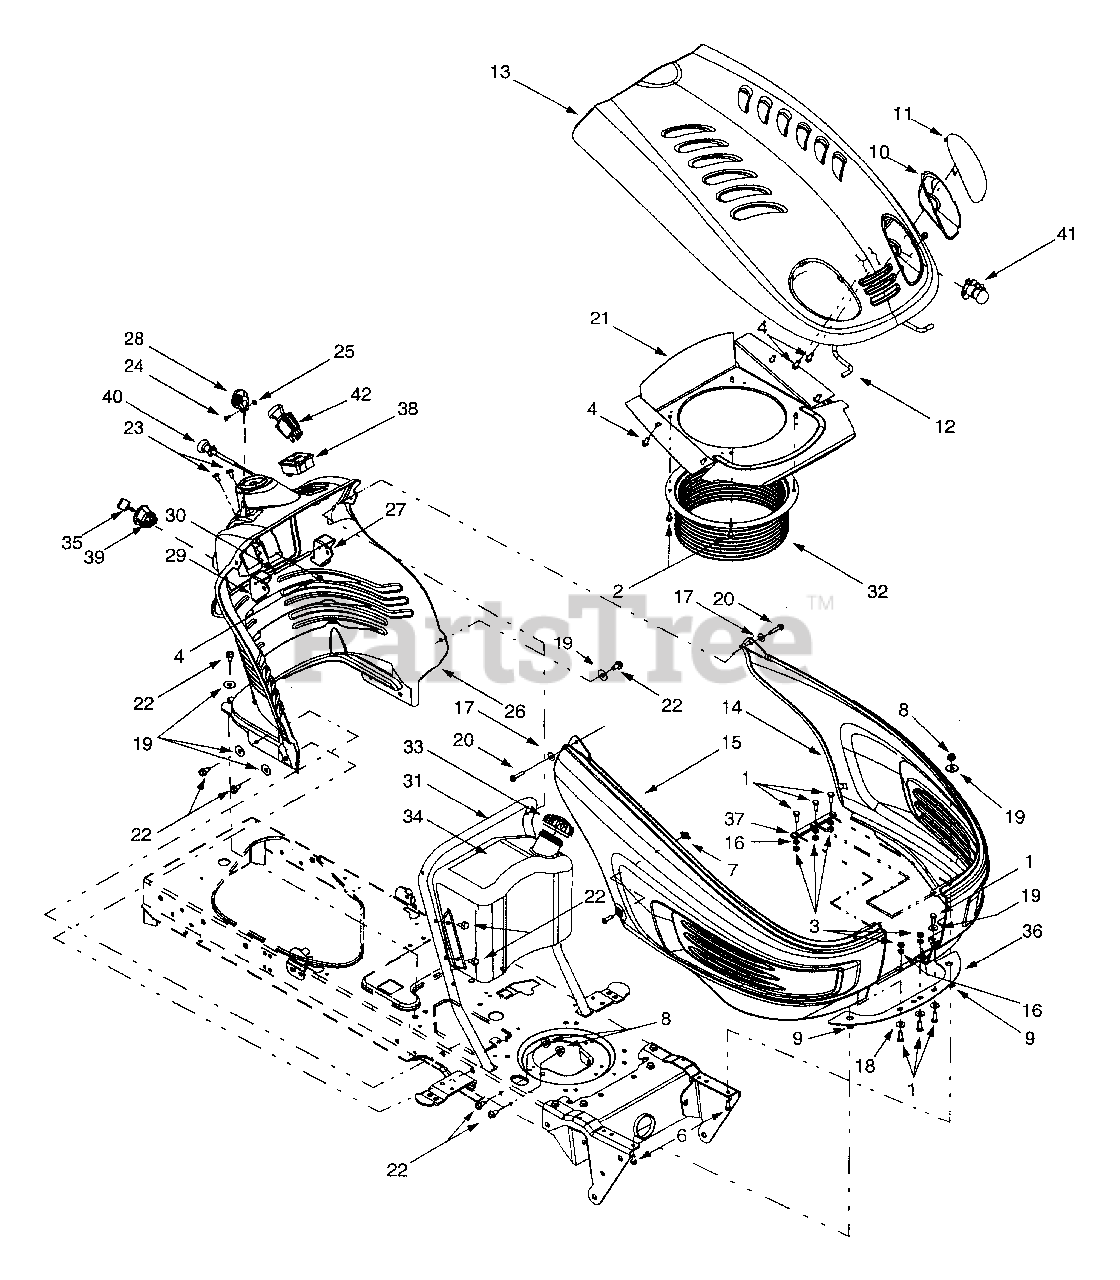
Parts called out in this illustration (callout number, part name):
1	Hex Cap Screw, 1/4-20 x .75
2	Self-tapping Screw, 1/4-20 x .5
3	Hex Nut, 1/4-20
4	Self-tapping Screw, 1/4-15 x .75
6	Hex Cap Screw, 5/16-18 x 1.25
7	U-type Speed Nut, 1/4-20
8	Flange Lock Nut, 5/16-18
9	Speed Nut
10	RH Headlight Reflector
11	RH Headlight Lens
12	Hood Support Rod
13	Hood
14	LH Side Panel
15	RH Side Panel
16	Lock Washer, 1/4
17	Flat Washer, .283 x .75 x .030
18	Flat Washer, .28 x .74 x .063
19	Flat Washer, .349 x 1.0 x .063
20	Self-tapping Screw, 1/4-20 x 1.25
22	Self-tapping Screw, 5/16-18 x .625
23	Torx Self-tapping Screw, 1/4-14 x .625
24	Torx Screw, #8-32 x .375
25	Hex Nut, 8-32
26	Dash Panel, 4-style
27	Parking Brake Button
28	Throttle Control Lever
29	Cruise Control Button
30	Brake/Cruise Pivot Rod
33	Fuel Cap
34	Fuel Tank, 3-gallon
35	Ignition Key w/ plastic cover
36	Heat Shield
39	Ignition Switch
40	Choke Knob/Cable
41	Headlight Assembly
42	Electric PTO Switch
